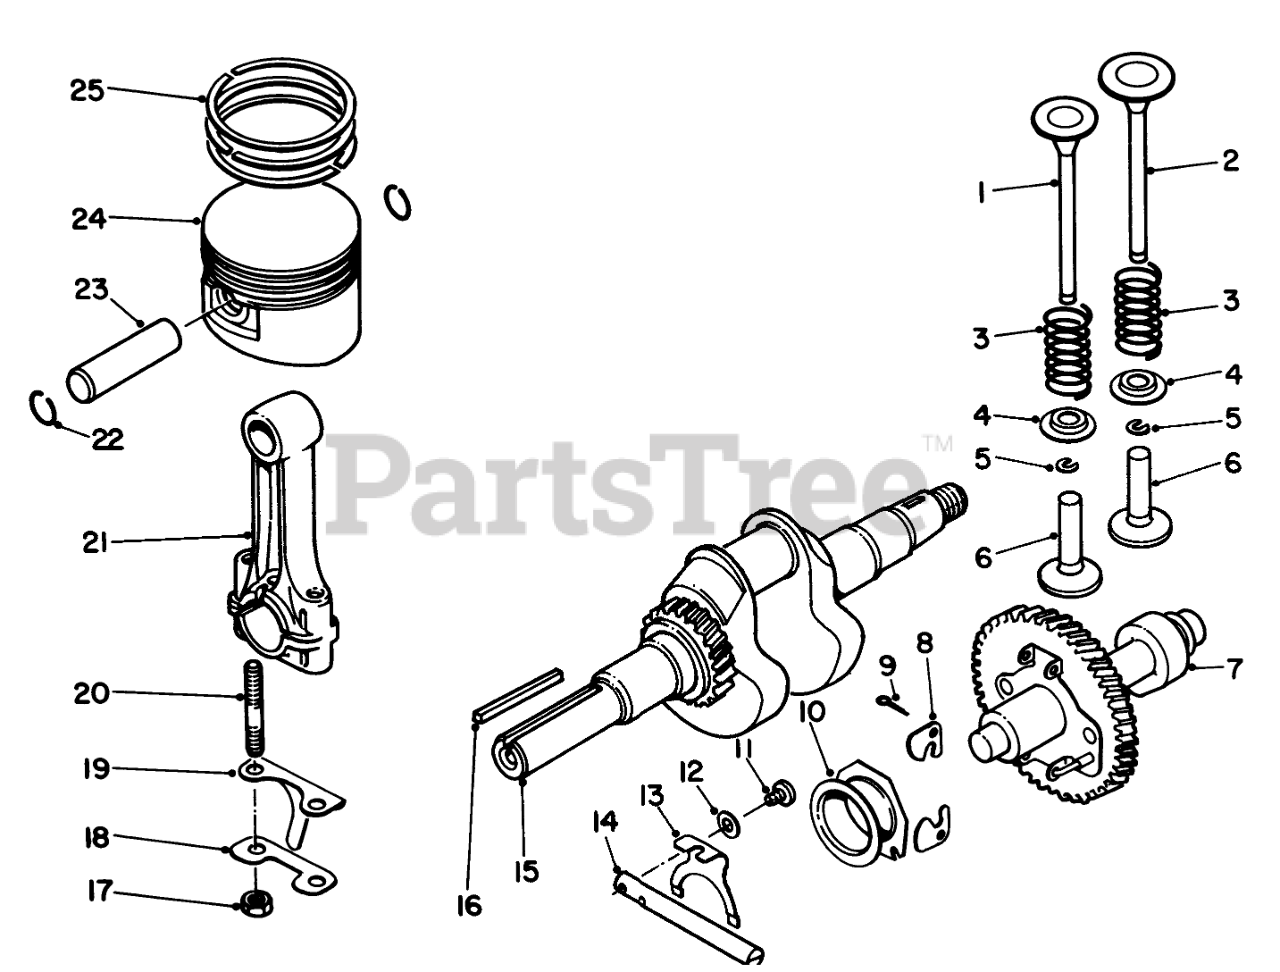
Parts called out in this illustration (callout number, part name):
1	Valve-Exhaust
2	Valve-Intake
3	Spring-Valve
4	Retainer
5	Cotter
6	Tappet (L:36.39)
7	Cam Shaft
9	Cotter Pin
10	Spacer
11	SCREW
12	Washer
13	Plate-Shift
14	Shaft-Throttle Return
18	LOCK PLATE
19	PLATE
20	Stud Bolt
21	Connecting Rod Assembly (Std.) (Incl. Ref. #17-20)
22	CIRCLIP
23	PISTON PIN
24	Piston Std.
25	Ring Set-Piston Std.
